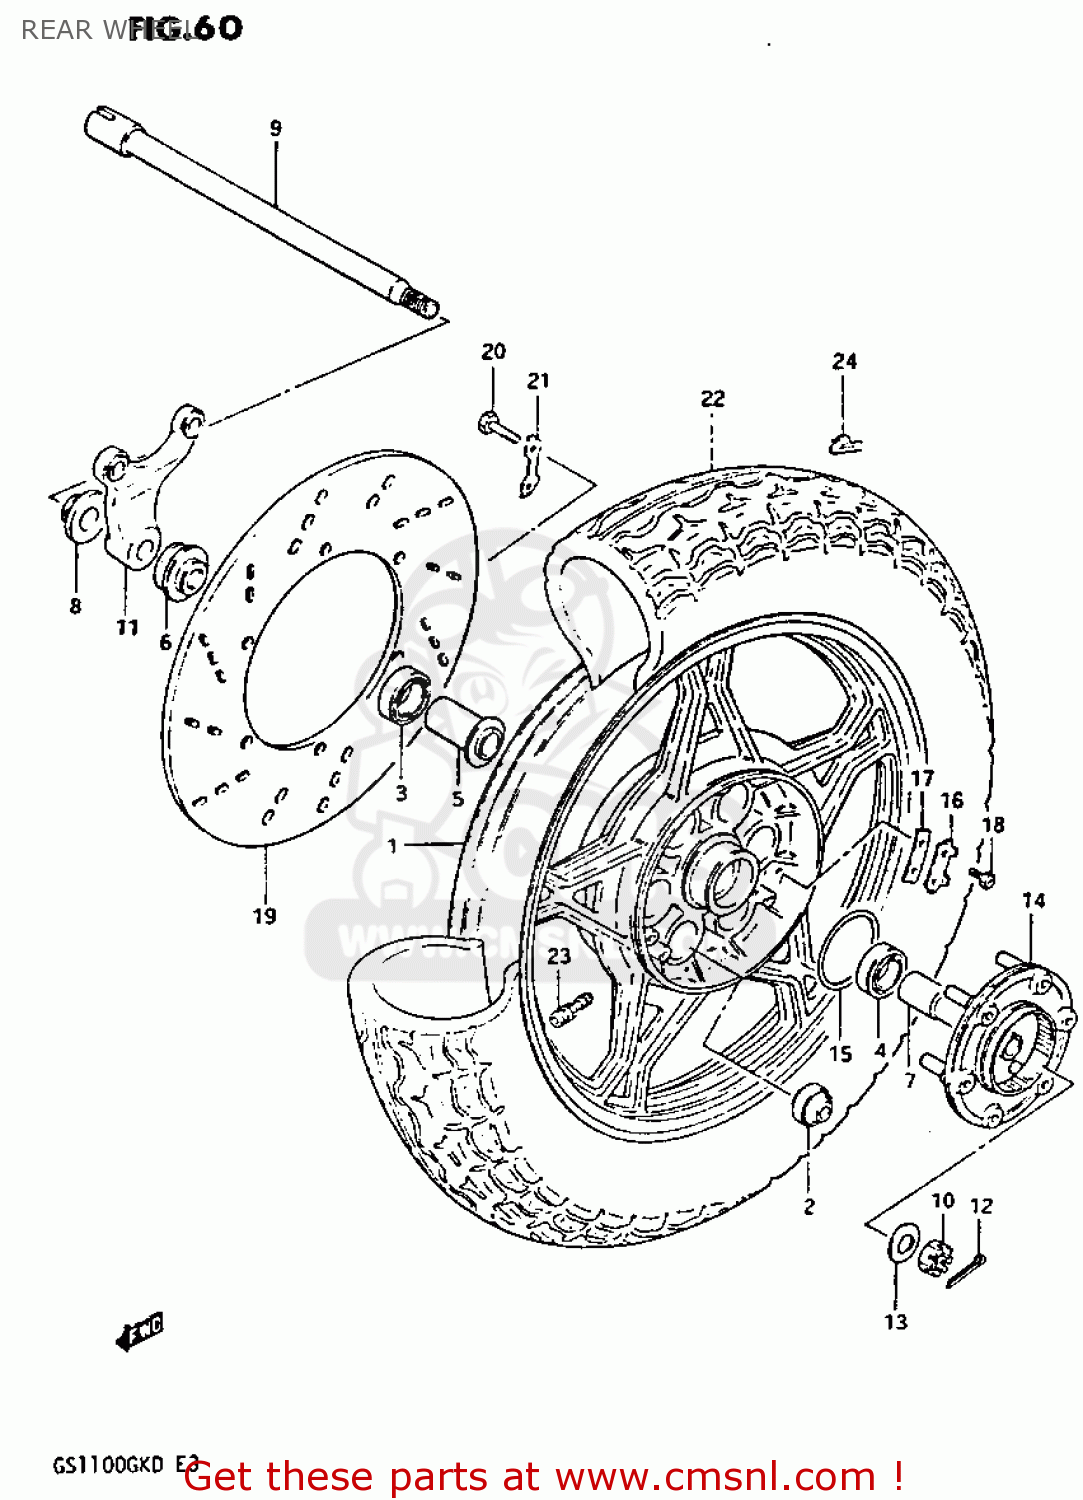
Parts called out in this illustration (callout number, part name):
1	CASTING WHEEL,REAR
2	BUSH
3	BEARING
4	BEARING
5	SPACER,REAR HUB BEARING
6	SPACER,REAR CALIPER BRACKET
7	SPACER,REAR AXLE,LEFT
8	SPACER,REAR AXLE,RIGHT
9	AXLE,REAR
10	NUT
11	BRACKET,RR,CALIPER
12	PIN,COTTER
13	WASHER (17.5X36X3.2)
14	JOINT ASSY,RR HUB DRIVEN
15	O RING(D:2.1,ID:65)
16	WASHER
17	WASHER,THRUST(T:1.6)
18	BOLT(6X16)
19	DISC,RR BRAKE
20	BOLT(8X25)
21	WASHER
22	TIRE
23	VALVE ASSEMBLY,WHEEL RIM,J
24	BALANCER,WHEEL
